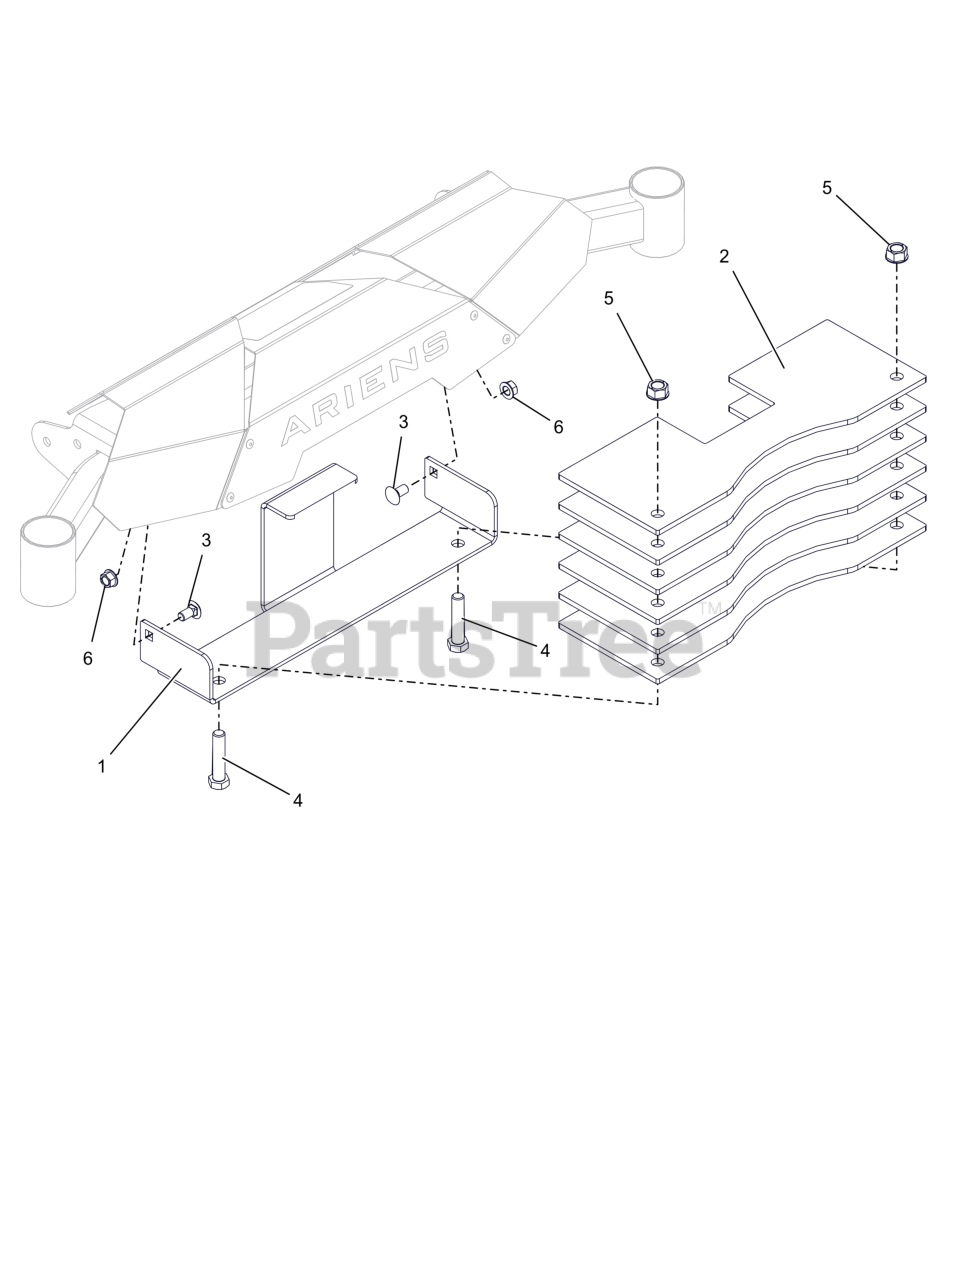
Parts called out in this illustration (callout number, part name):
1	BRACKET, WEIGHT -BAGGER
2	WEIGHT, BAGGER
3	@BLT-RDHDSQNK .38-16X.75 G5YZ
4	@BLT-HEX .50-13X2.25 GR5 YWZC
5	@NUT-LK-TOP-FLG .50-13 YWZC
6	@NUT-LK-TOP-FLG .38-16 YWZC
